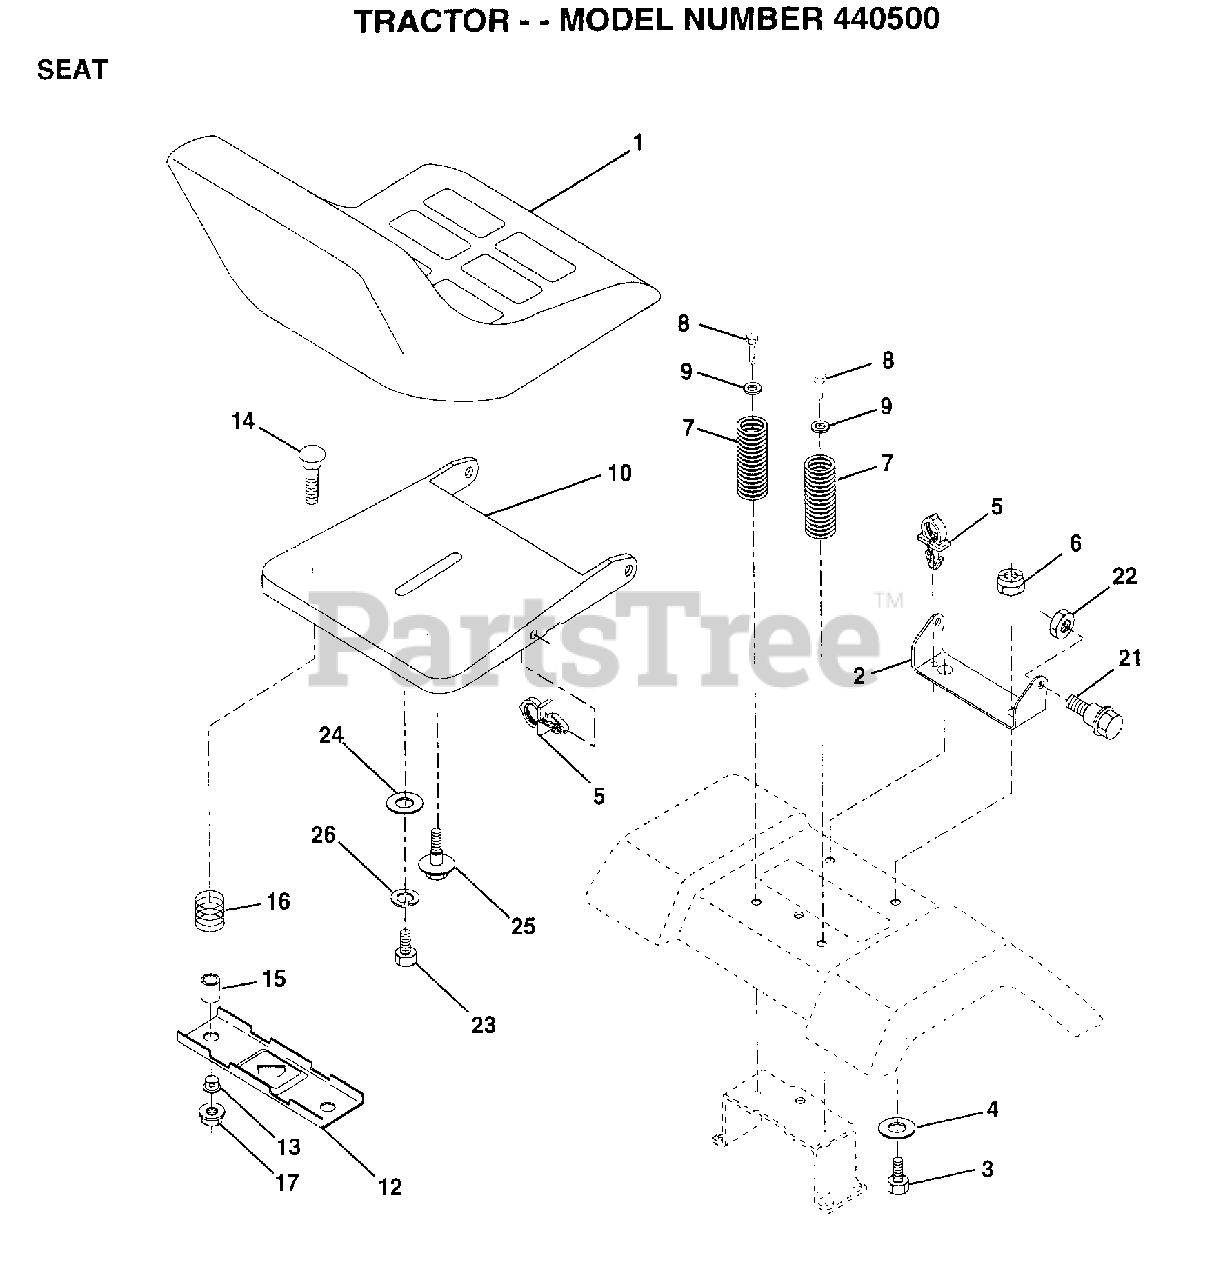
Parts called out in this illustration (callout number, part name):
2	BRACKET PVT SEAT
3	BOLT
4	WASHER PM
5	CLIP.PUSH-IN.HING
6	NUT
7	SPRING COMPRESSIO
8	SCREW GTV
9	WASHER
12	BRKT SWITCH
13	BUSHING
15	SPLIT SPACER
16	SPRING
21	BOLT.SHLD.5/16-18
22	NUT
23	BOLT
24	WASHER
25	"BOLT,SHOULDER"
26	LOCKWASHER
